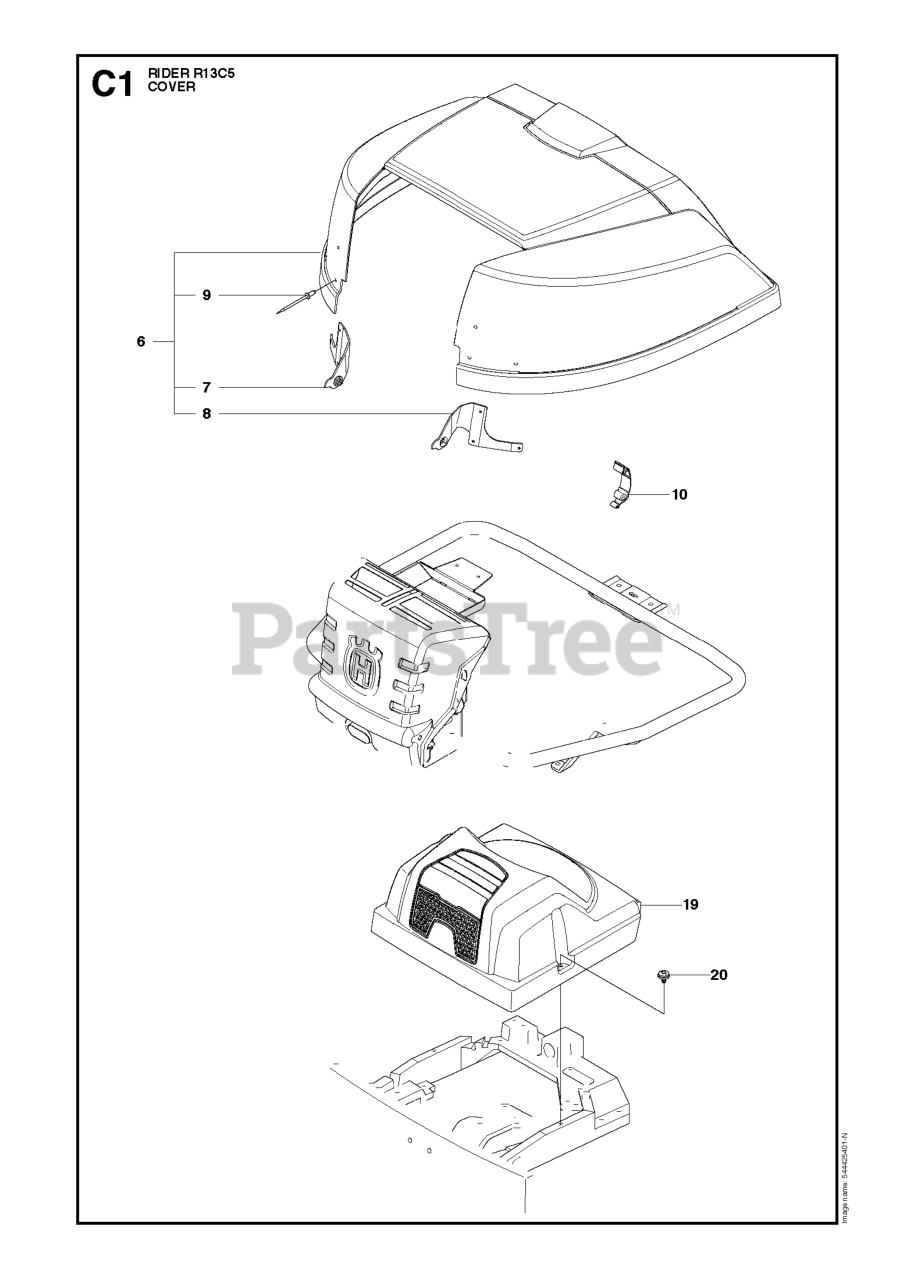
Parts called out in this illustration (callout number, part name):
7	HINGE LEFT
8	HINGE RIGHT
10	CLIP GRAY
19	RP COVER
